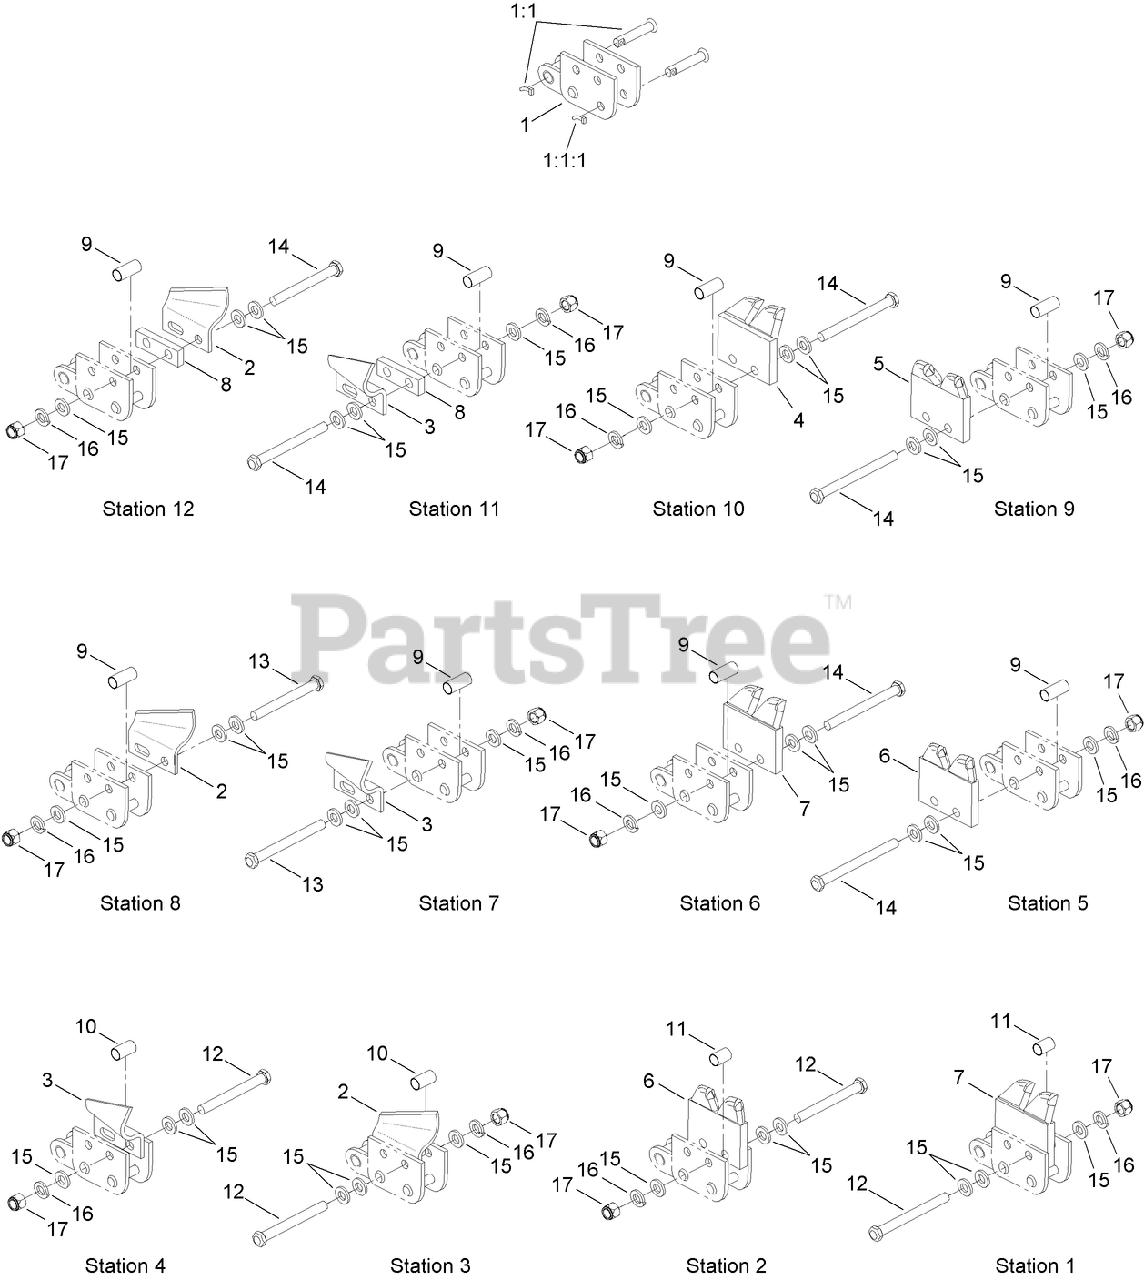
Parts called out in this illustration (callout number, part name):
1	CHAIN REPAIR LINK ASM
1:1	NOTCHED PIN AND KEEPER ASM
1:1:1	PIN-KEEPER
2	CUTTER-CUP, MIXED, LH
3	CUTTER-CUP, MIXED, RH
4	TOOTH-TERMINATOR, LH
5	TOOTH-TERMINATOR, RH
6	TOOTH-TERMINATOR, RH
7	TOOTH-TERMINATOR, LH
8	SPACER-FLAT
9	SPACER-TUBE, OUTSIDE MOUNT
10	SPACER-TUBE, INSIDE CUP MOUNT
11	SPACER-TUBE, INSIDE ADAPTER
12	BOLT-HH
13	BOLT-HH
14	BOLT-HH
15	WASHER-FLAT
16	WASHER-LOCK
17	NUT-LOCK
